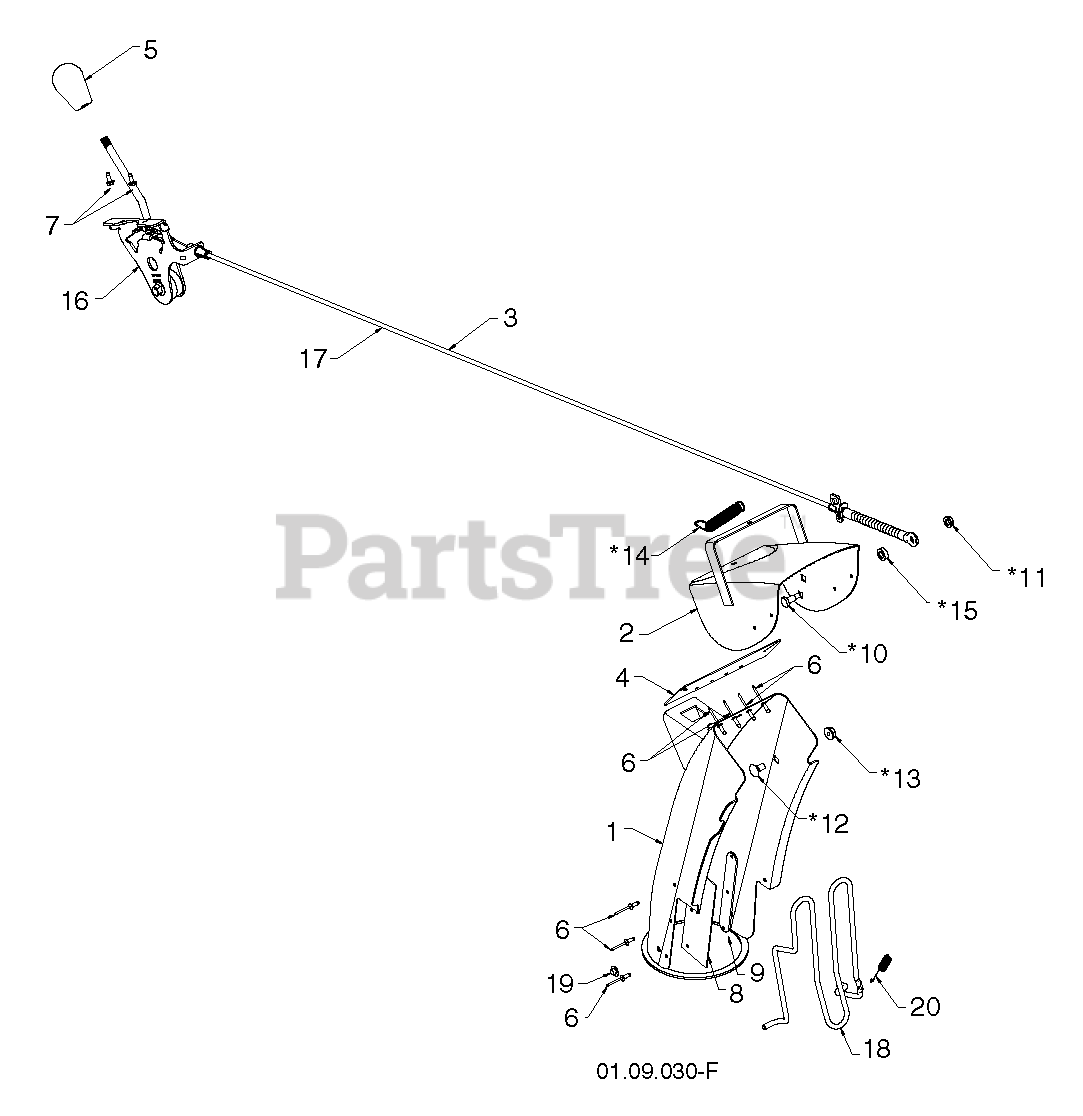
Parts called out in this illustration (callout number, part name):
1	ASM.CHUTE/DEFLECTOR.668
3	CONTROL.ASM.DEFLEC.BLK.BOWDEN
5	KNOB.OVERMOLD.DS.HUSQVARNA/BLK
10	BOLT.CARR.W.3125 SHLDR..25-20
11	NUT.HEX.FLANGE.1/4
12	BOLT CAR BLK 5/16-18 X 5/8
13	LOCKNUT-FLANGE 5/16-18
14	SPRING.DEFLECTOR.REM.CHUTE
15	WASHER.NYLON.326 X.625 X.205
16	RP CNTRL.HEAD.ASSEM.DEFLECTOR
17	RP CABLE.DEFLECTOR.CONTRL.BOWD
18	ROD.GUARD.CHUTE (2 2)
19	NUT
20	SPRING.CHUTE.GUARD
